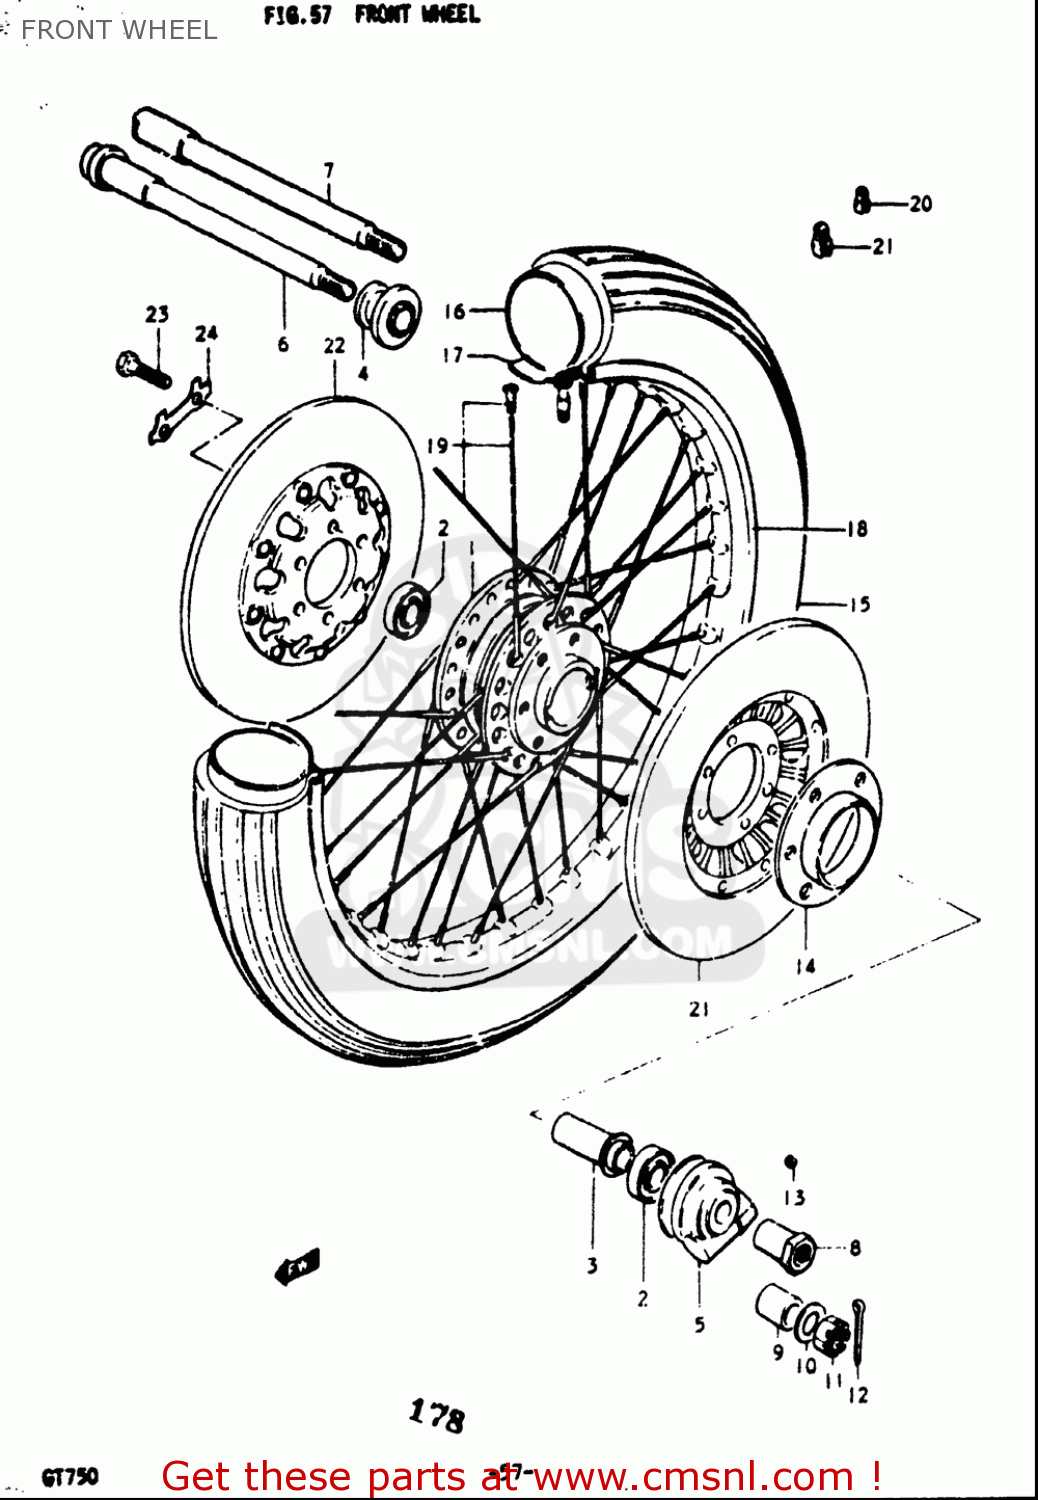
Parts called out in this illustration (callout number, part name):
1	HUB,FRONT WHEEL
3	SPACER,FR HUB BEARING
4	SPACER,FR AXLE,R
5	BOX ASSY,SPEEDOMETER GEAR
6	AXLE,FRONT
7	AXLE,FRONT
9	SPACER(15X22X30)
10	WASHER
11	NUT 12MM
12	PIN
13	SEAL,OIL(6X10X3)
16	TUBE ASSEMBLY,WHEEL,INNER
17	PROTECTOR,WHL INR TUBE
18	RIM,FR WHEEL
19	SPOKE ASSY,FR
20	BALANCER,WHEEL (B)
21	BALANCER,WHEEL (30G)
23	BOLT(8X30)
24	WASHER
